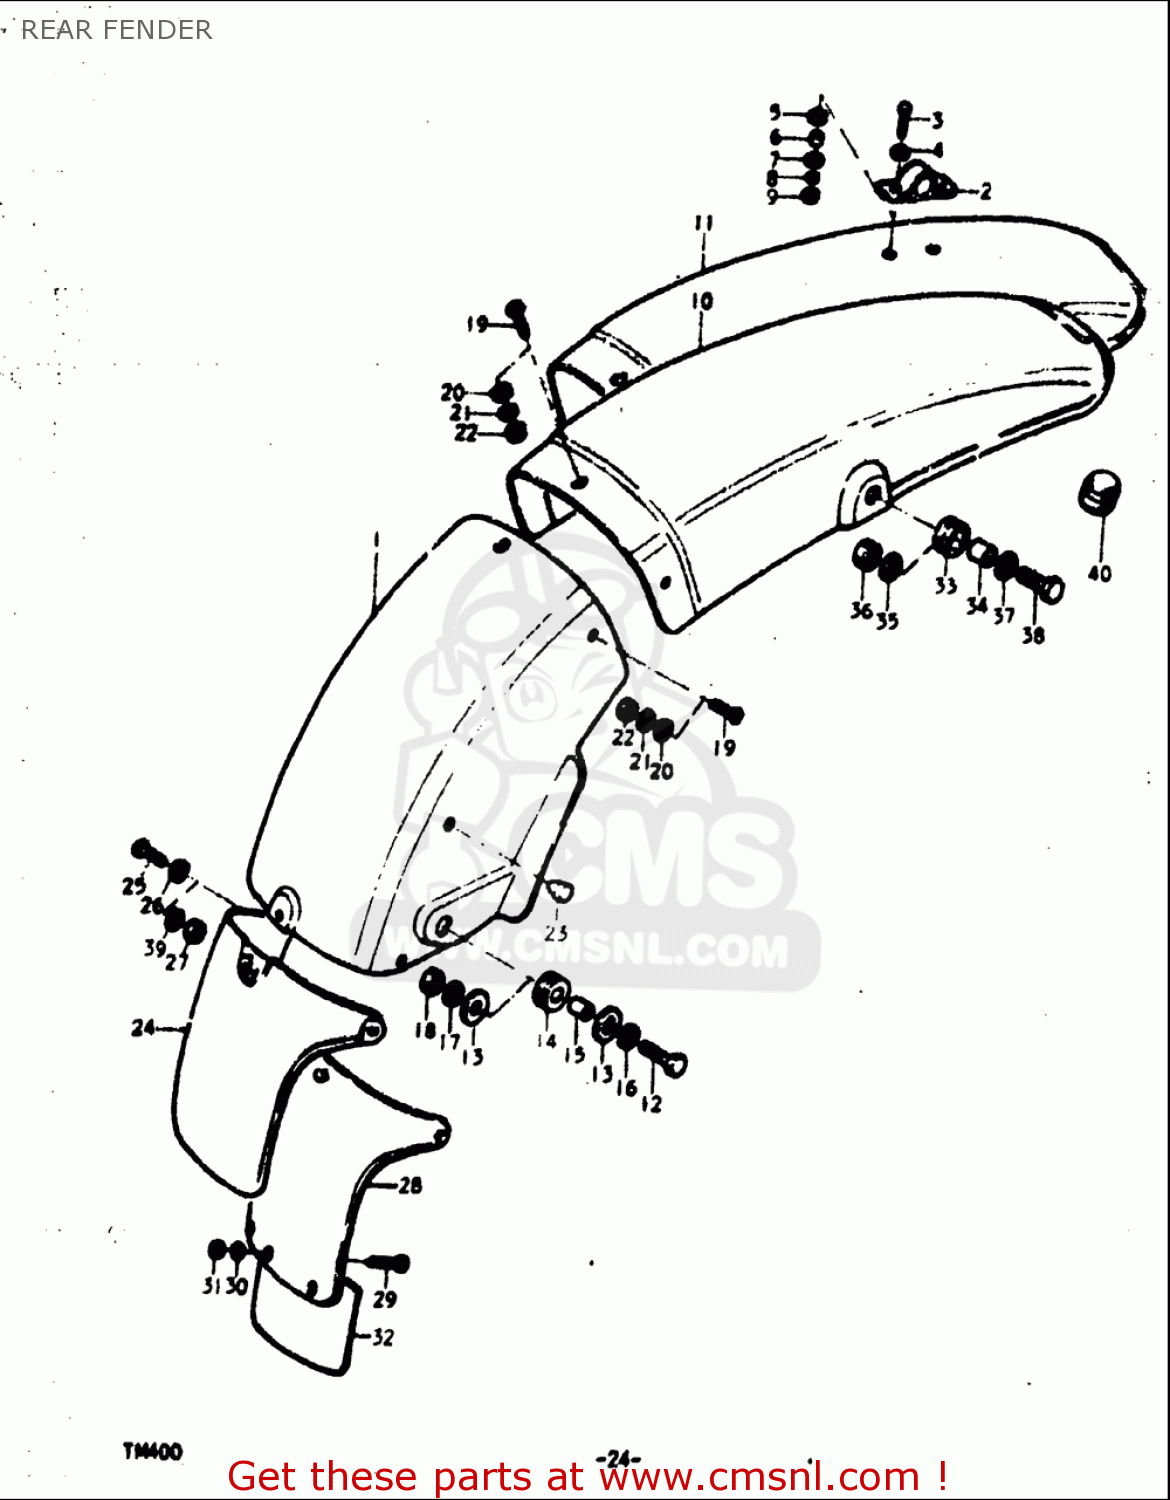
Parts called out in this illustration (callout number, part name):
3	BOLT(6X18)
4	WASHER
5	CUSHION
6	SPACER(6.5X10X7)
7	WASHER(6.5X20X1.2)
8	WASHER,LOCK
9	NUT
12	BOLT
13	WASHER(6.5X20X1.2)
14	CUSHION
15	SPACER(6.1X9X7.5)
16	WASHER
17	WASHER,LOCK
18	NUT
19	SCREW
20	WASHER
21	WASHER,LOCK
22	NUT
23	CUSHION
25	SCREW
26	WASHER
29	SCREW
30	WASHER
31	NUT
32	GUIDE,RR FENDER MUD
33	CUSHION
34	SPACER(6.1X9X7.5)
35	WASHER,LOCK
36	NUT
37	WASHER(6.5X20X1.2)
38	BOLT
39	WASHER,LOCK
